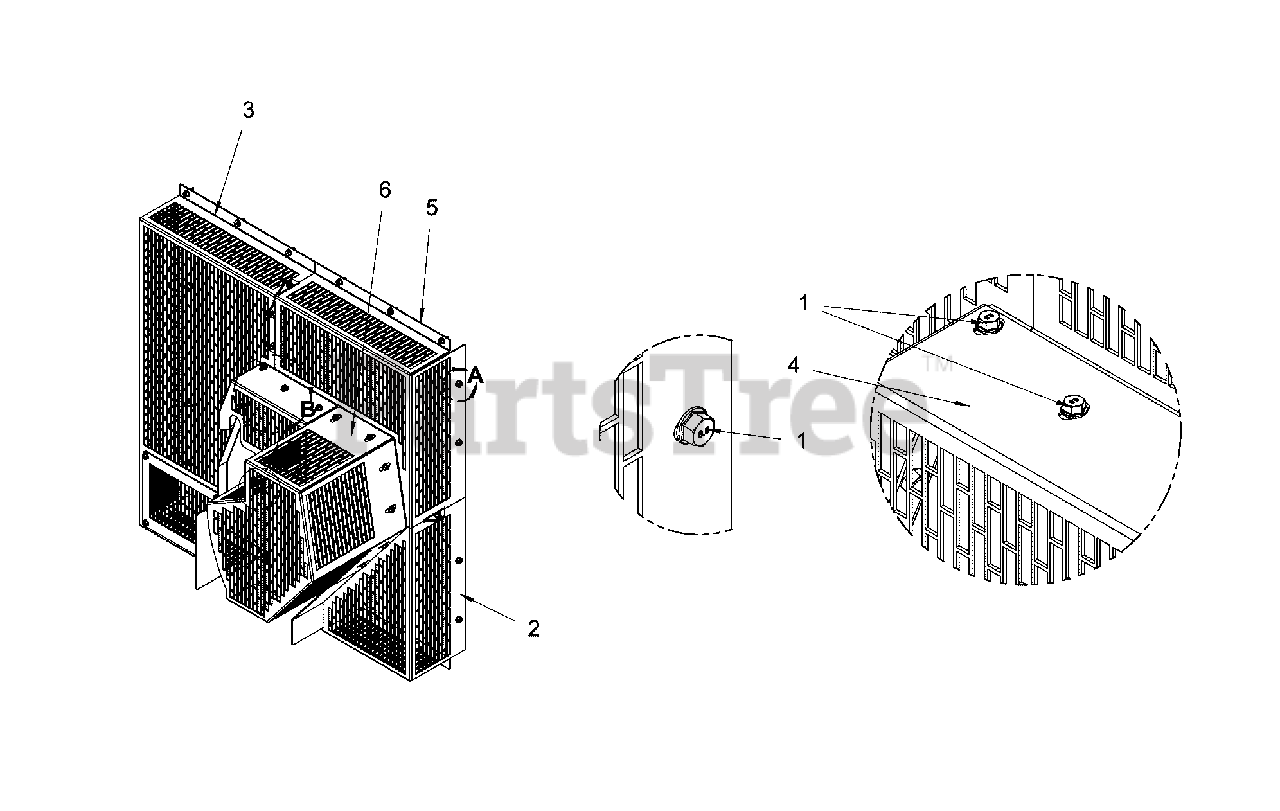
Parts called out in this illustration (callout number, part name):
1	* BOLT
2	* FAN GUARD
3	FAN GUARD
4	FAN GUARD
5	FAN GUARD
6	TIMING WHEEL GUARD
